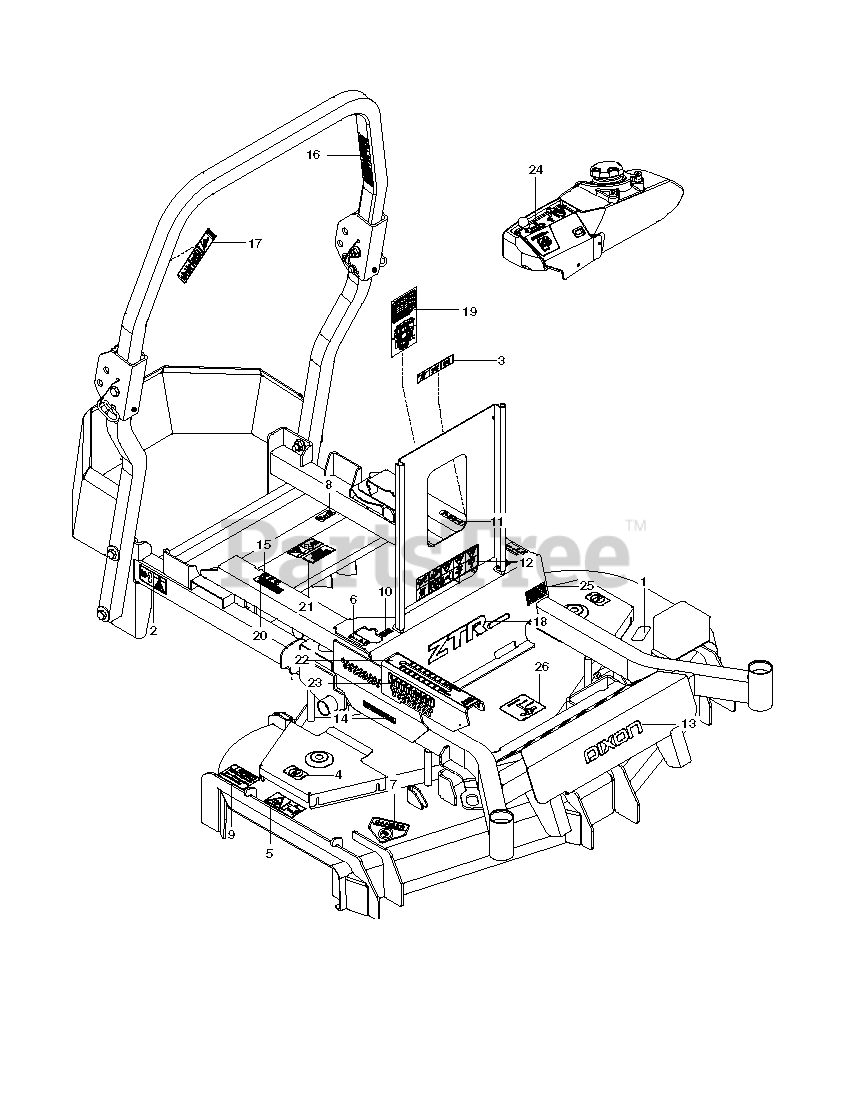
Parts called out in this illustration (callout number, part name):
2	DECAL, BELT DRIVE
4	DECAL, NO STEP
5	DECAL, EURO SEVERING
6	DECAL, MOTION CONTROL
7	DECAL, CPSC
8	DECAL, FUEL
9	DECAL, CAUTION
10	DECAL, TRACKING
11	DECAL, PARK BRAKE
12	DECAL, WARNING
14	DECAL, COMMERCIAL
16	DECAL, ROPS
17	DECAL, ROPS, WARNING
18	DECAL, DX200
19	DECAL, SERVICE
20	DECAL, WARNING SPARK ARRESTOR
22	DECAL, HEIGHT
23	DECAL, HEIGHT
25	DECAL, FLAG
26	DECAL, BELT ROUTING
